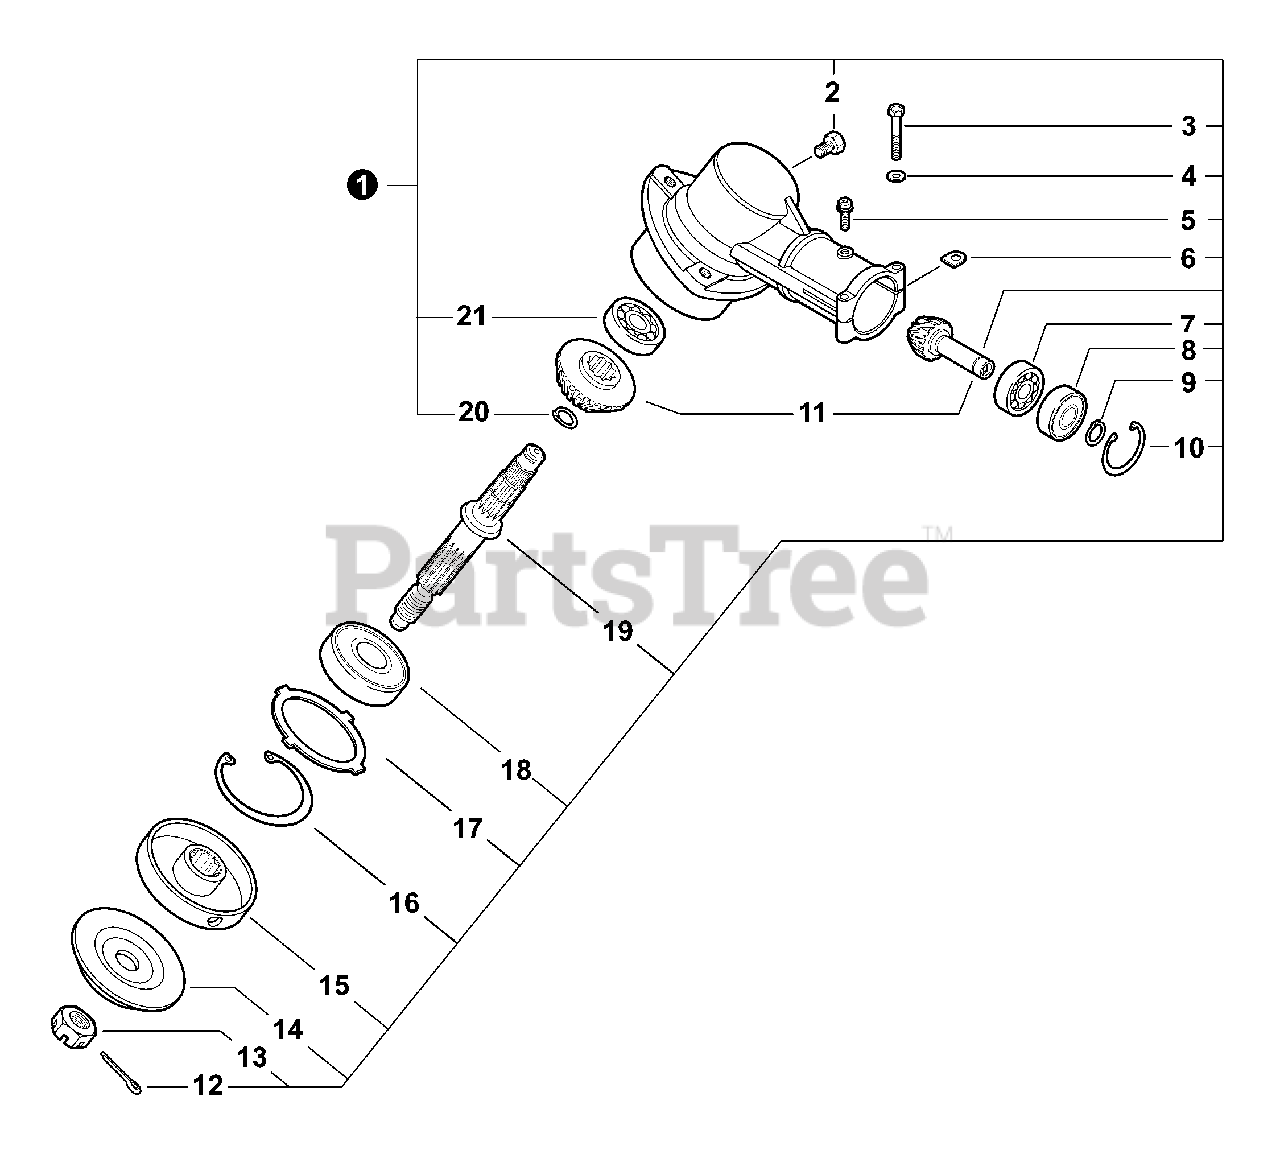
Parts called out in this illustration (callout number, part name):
1	GEAR CASE ASY
2	SCREW - 5×10
3	BOLT - 5×35
5	WASHER, SHIM
6	RING, RETAINING - 22
7	RING, RETAINING - 10
8	BEARING, BALL - 6900Z
9	BEARING, BALL - 6900
10	GEAR SET - BEVEL
11	BOLT - 8×8
12	PIN, SPLIT - 2×22
13	NUT - 10 -- LEFT HAND
14	ADAPTER, BLADE - LOWER
15	ADAPTER, BLADE - UPPER
17	RING, RETAINING - 32
18	BEARING, BALL - 6201
19	GEAR, SHAFT
20	RING, RETAINING - 12
21	BEARING, BALL - 609
